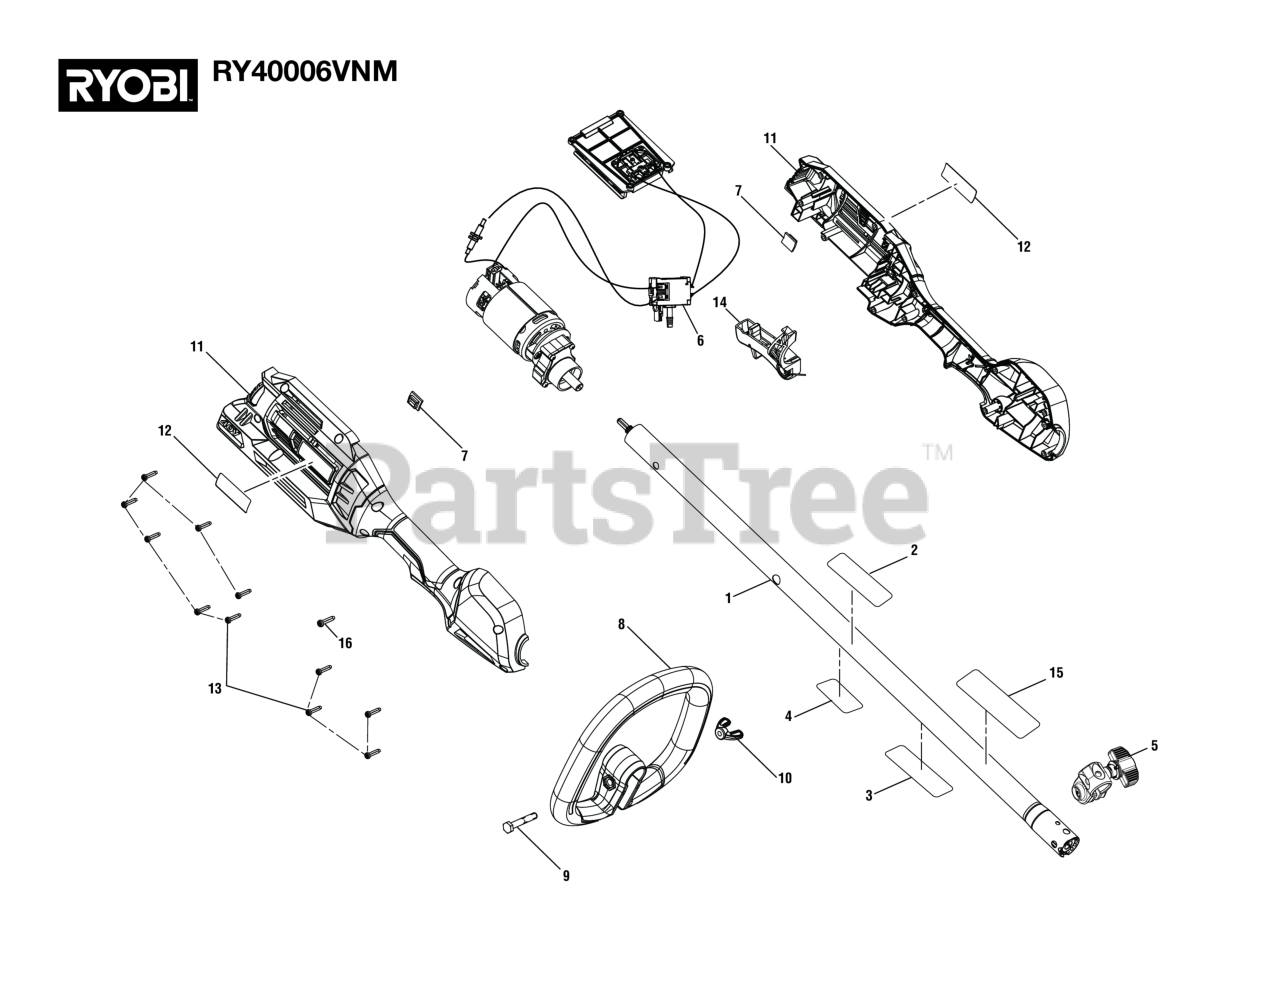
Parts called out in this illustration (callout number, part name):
1	Boom Assembly
2	Warning Icon Label
3	Warning Label (French/Spanish)
4	Data Label
5	Boom Clamp Assembly
6	Motor, Gear Box, Switch & Contact Plate Assembly
7	Rubber Bumper
8	Auxiliary Handle Assembly
9	Screw (1/4-20 x 40 mm, Cap Hex Hd.)
10	Wing Nut (1/4-20, Plastic)
11	Rear Handle Assembly (Inc. Key No. 12)
12	Logo Label
13	Screw (M4 x 18 mm, T15 Torx Pan Hd.)
14	Switch Trigger Assembly
15	Attachment Label
16	Screw (M3.5 x 16 mm, T10 Torx Pan Hd.)
